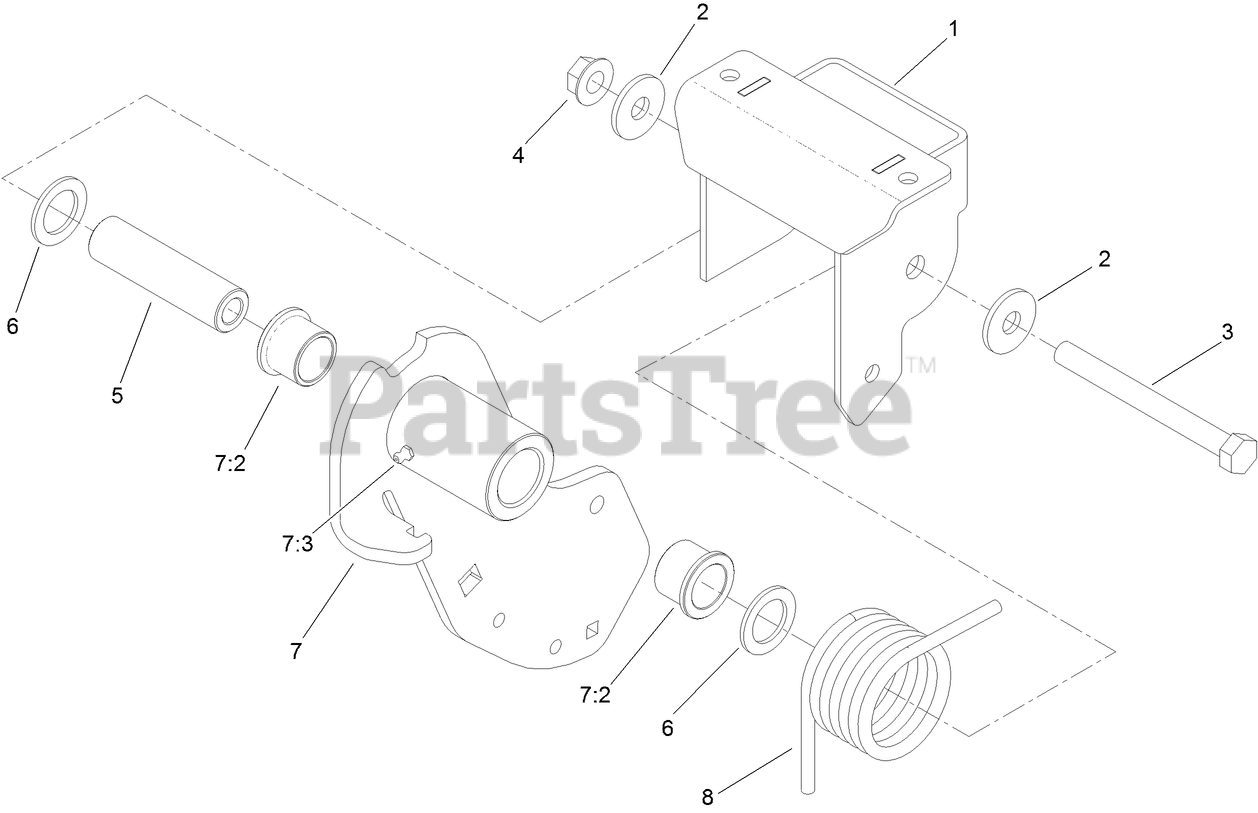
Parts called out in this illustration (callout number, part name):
1	BRACKET-TENSIONER, IDLER
2	WASHER-SUPPORT
3	SCREW-HH
4	NUT-HF
5	SPACER-PLAIN
6	SPACER-HARDENED
7	IDLER TENSIONER ARM ASM
7:2	BUSHING-FLANGE
7:3	FITTING-GREASE
8	SPRING-TORSION
